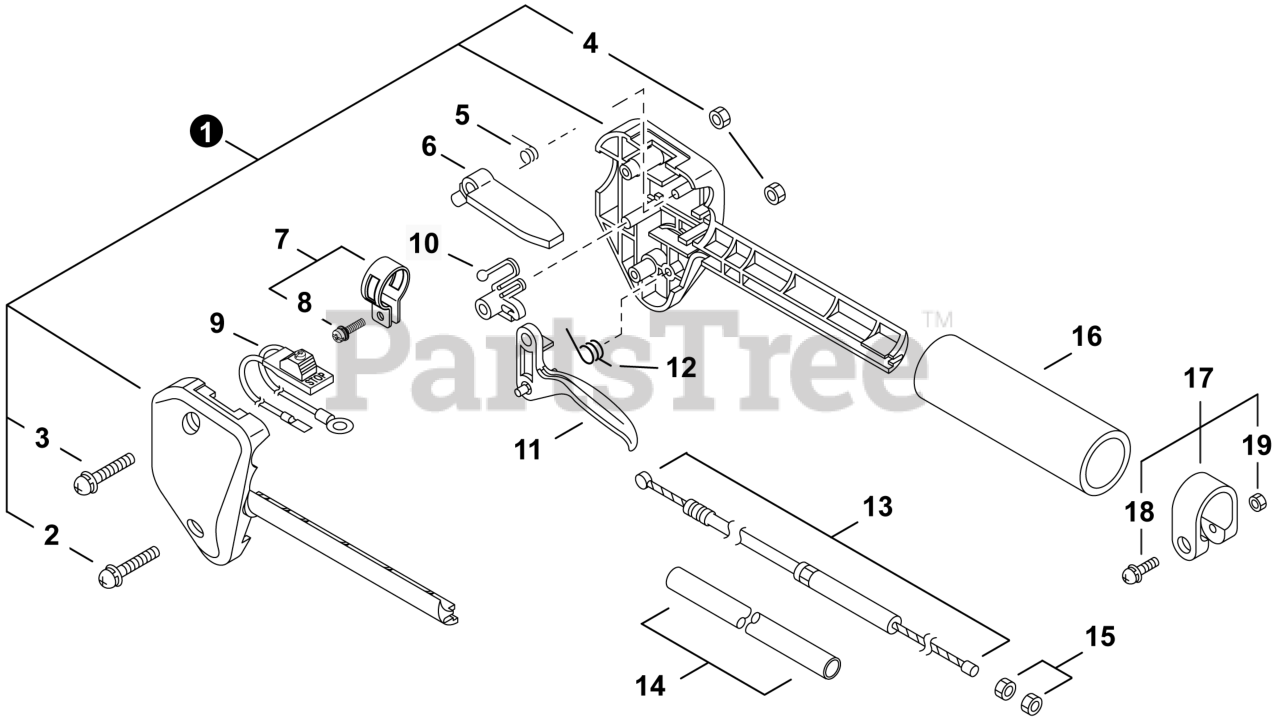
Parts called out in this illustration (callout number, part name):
1	HANDLE KIT, CONTROL
2	SCREW 5x25
3	SCREW 5x35
5	SPRING, TORSION
6	LEVER, THROTTLE LOCKOUT
7	CLAMP KIT
8	SCREW 5x14
9	SWITCH, ON-OFF
10	LOCKOUT, THROTTLE
11	TRIGGER, THROTTLE
12	SPRING, TORSION
13	CABLE, THROTTLE
14	TUBE, FLEXIBLE
16	GRIP, HANDLE
17	CLAMP KIT
18	SCREW 5x28
